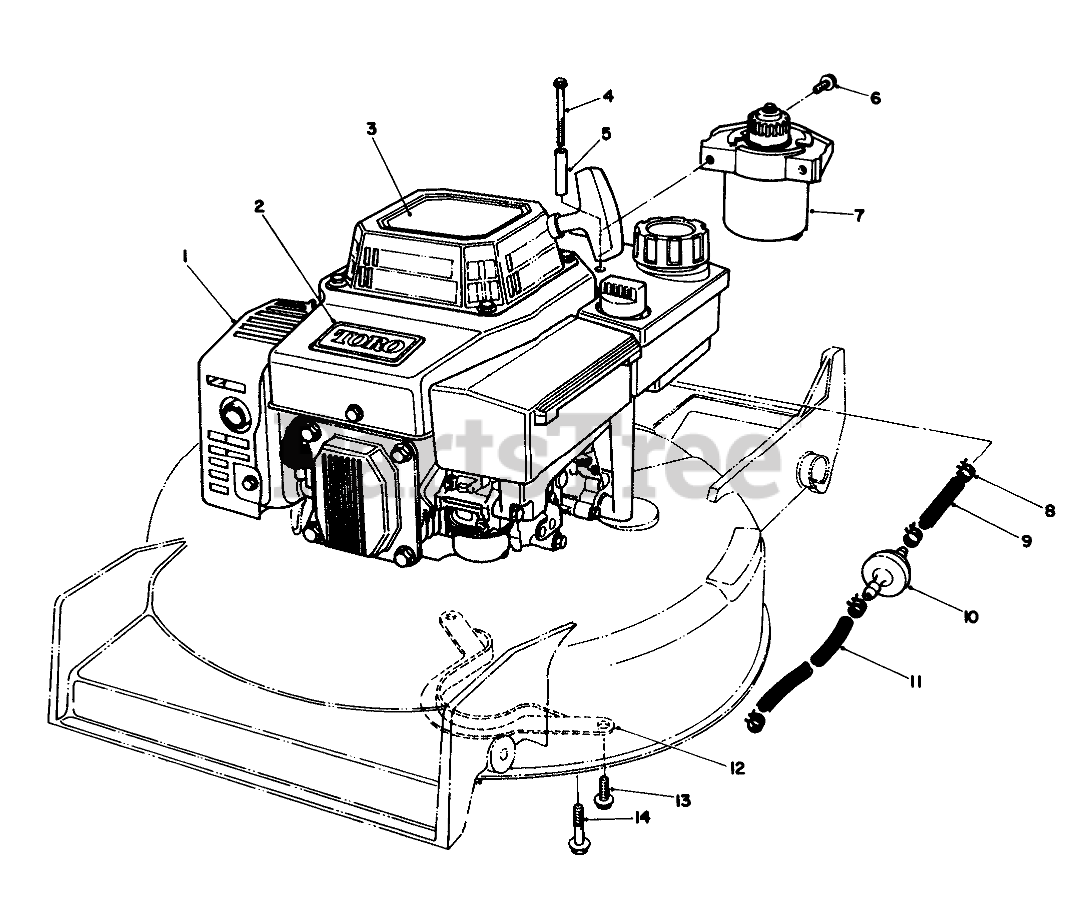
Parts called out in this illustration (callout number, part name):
1	Engine-OHV
2	TORO LOGO PLT
3	DECAL - RECOIL GTS
4	THRD FORMING SCREW
5	TUBULAR SPACER
6	SCREW
7	STARTER MOTOR ASM
8	CLAMP-FUEL LINE
9	LINE-GAS
10	FILTER-FUEL
11	HOSE-FUEL
12	BBC BELT GUIDE
13	SCREW-HWHTF
14	SCREW-HWHTF
